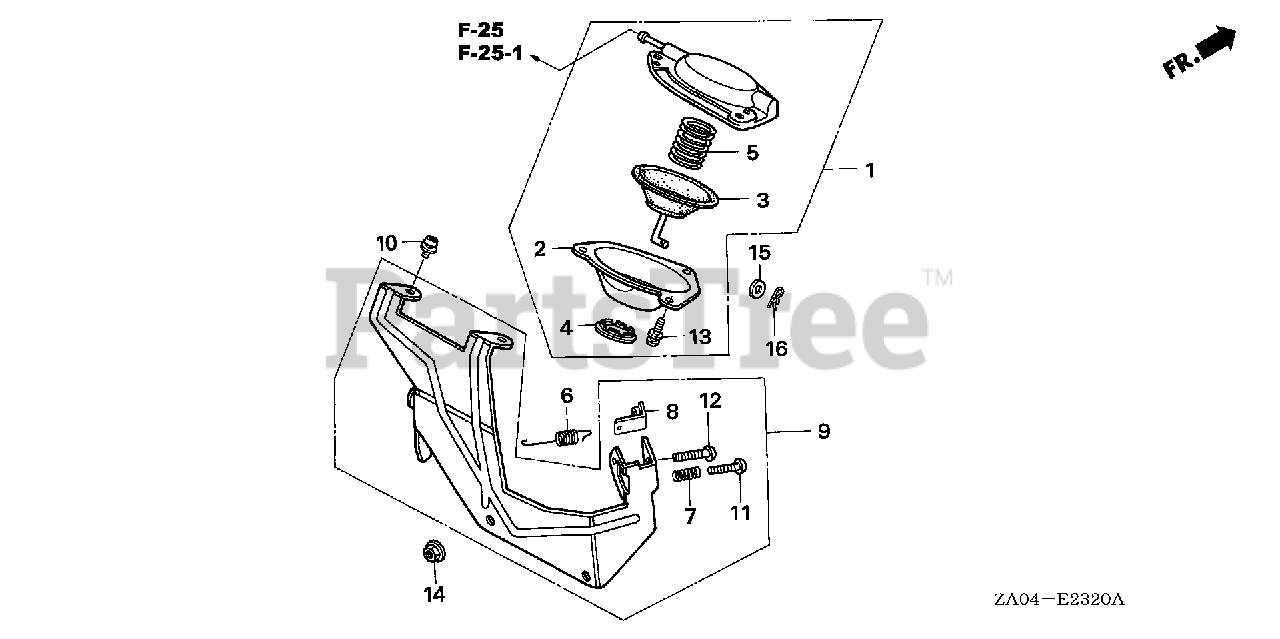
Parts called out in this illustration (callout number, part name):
1	DIAPHRAGM ASSY.
2	COVER, DIAPHRAGM
4	BUSH, DIAPHRAGM COVER
5	SPRING, COIL
6	SPRING, GOVERNOR (NOT AVAILABLE)
7	SPRING, CONTROL ADJUSTING
8	PLATE, CONTROL
9	CONTROL ASSY. (NOT AVAILABLE)
10	SCREW-WASHER (5X8)
11	SCREW, PAN (4X16)
12	SCREW, PAN (6X28)
13	SCREW-WASHER (4X8)
14	NUT, FLANGE (6MM)
15	WASHER, PLAIN (4MM)
16	PIN, LOCK (4MM)
